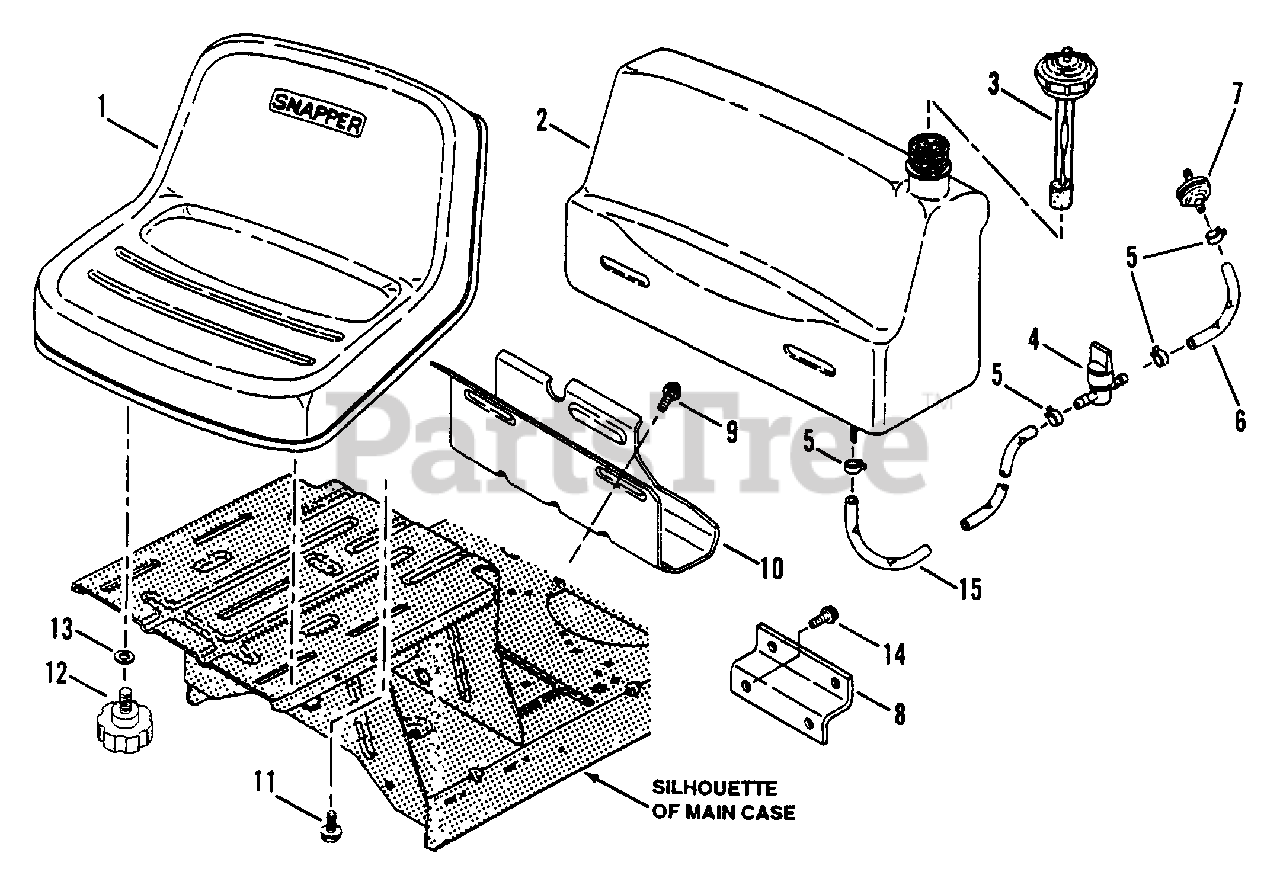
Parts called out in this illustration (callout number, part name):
1	SEAT, Operator
2	ASSEMBLY, Fuel Tank
3	CAP, Fuel Tank (w/gauge)
4	VALVE, Fuel Shut-Off
5	CLAMP, Fuel Line
6	HOSE, Fuel (5" Long)
7	FILTER, Fuel (In-Line)
8	BRACKET, Tank
9	SCREW,5/16-18 x 5/8" Self-Tapping
10	BRACKET, Fuel Tank (Rear)
11	BOLT, 5/16-18 x 1/2" Hex Flange Lock
12	KNOB, Seat Adjusting
13	SPACER, 5/16
14	SCREW, 5/16-18 x 1/2" Self-Tapping
15	HOSE, Fuel (24-1/4" Long)
